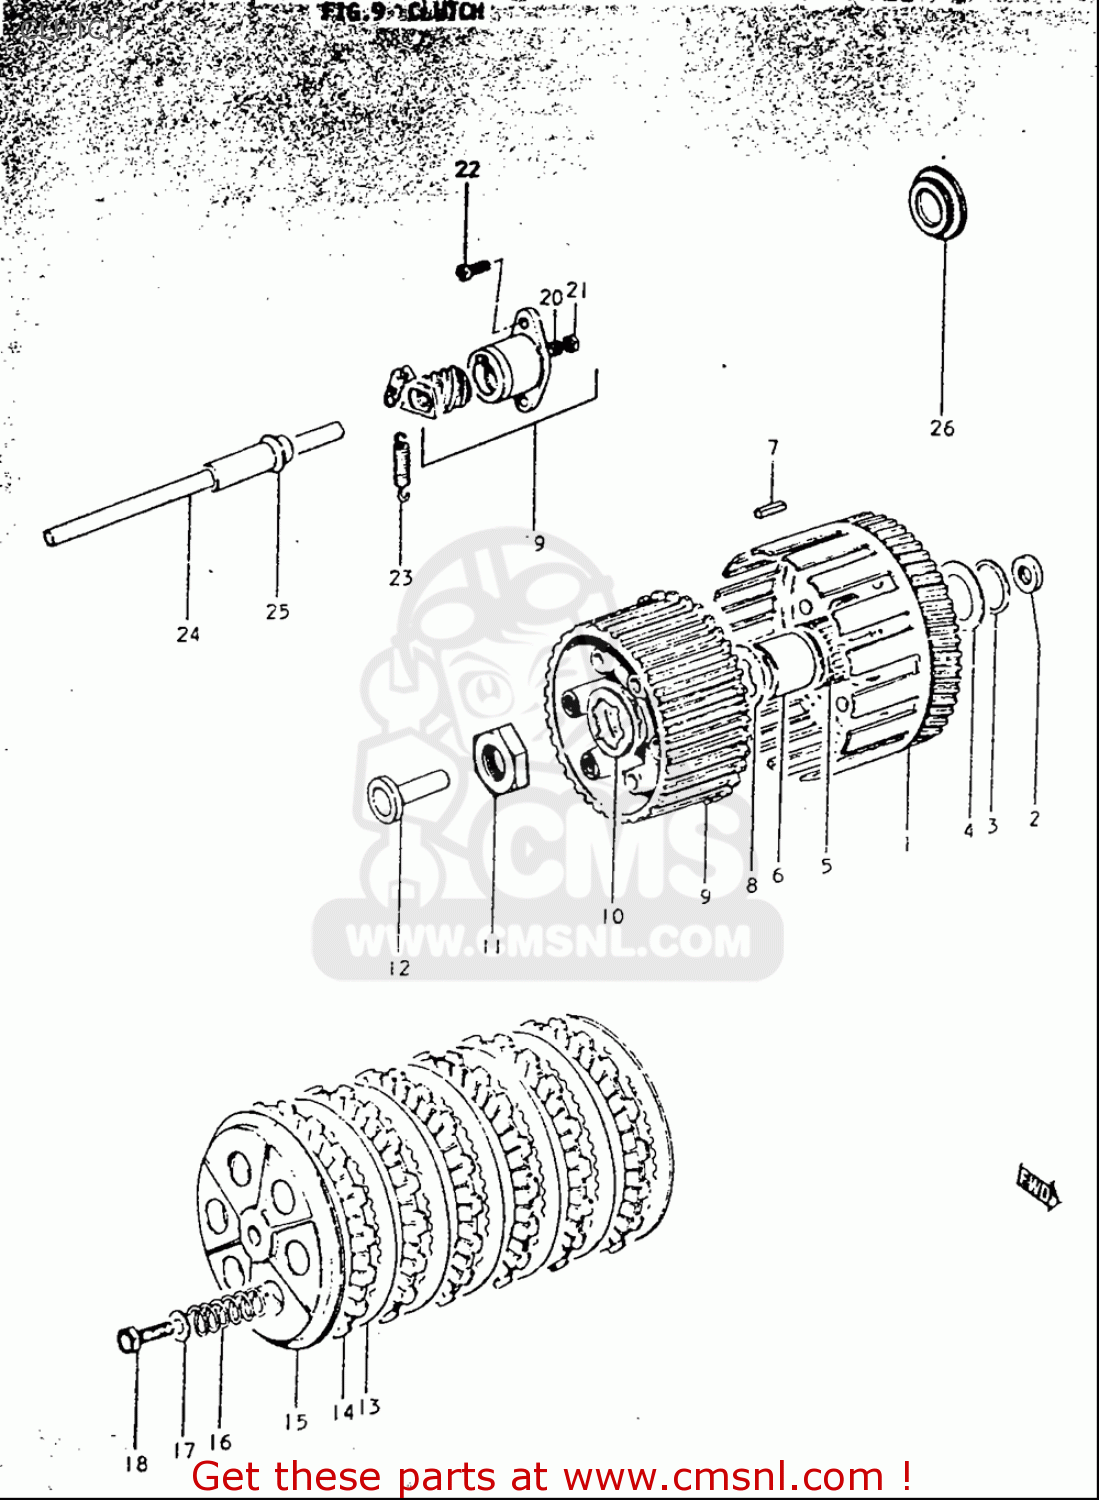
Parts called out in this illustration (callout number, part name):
2	SEAL,OIL(8X17X5)
3	WASHER
4	WASHER
8	WASHER(20X44X3)
10	WASHER,LOCK
11	NUT
13	PLATE,CLUTCH DRIVEN(T:2.0) (NAS)
16	SPRING
17	WASHER(6.5X20X1.6)
20	SCREW
21	NUT
22	SCREW
23	SPRING
24	ROD,CLUTCH PUSH
25	DUST SEAL
26	CAP(OD:36)
